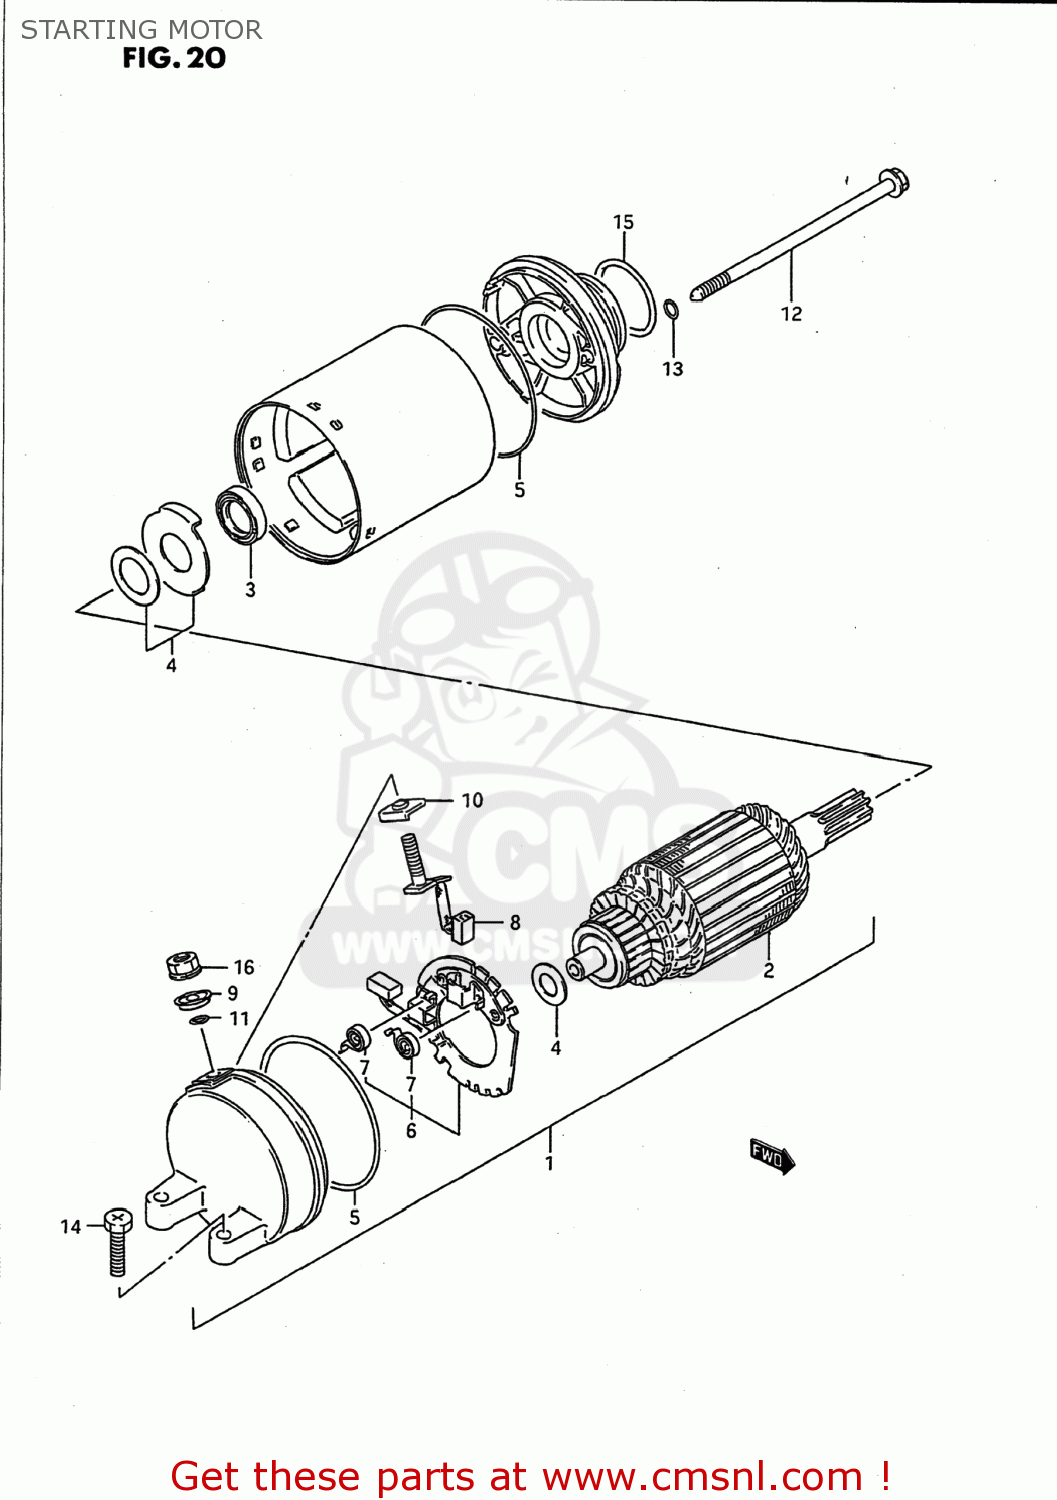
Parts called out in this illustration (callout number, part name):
1	MOTOR ASSEMBLY,STARTING
2	ARMATURE
3	SEAL,OIL
4	SHIM SET,STARTING MOTOR
5	O RING
6	HOLDER,BRUSH
7	SPRING
8	BRUSH SUB ASSY,STARTING MOTOR
9	BUSHING
10	BUSH,B
11	O RING
12	BOLT
13	O RING
14	SCREW (6X25)
15	O RING(D:3,ID:24.5)
16	NUT
